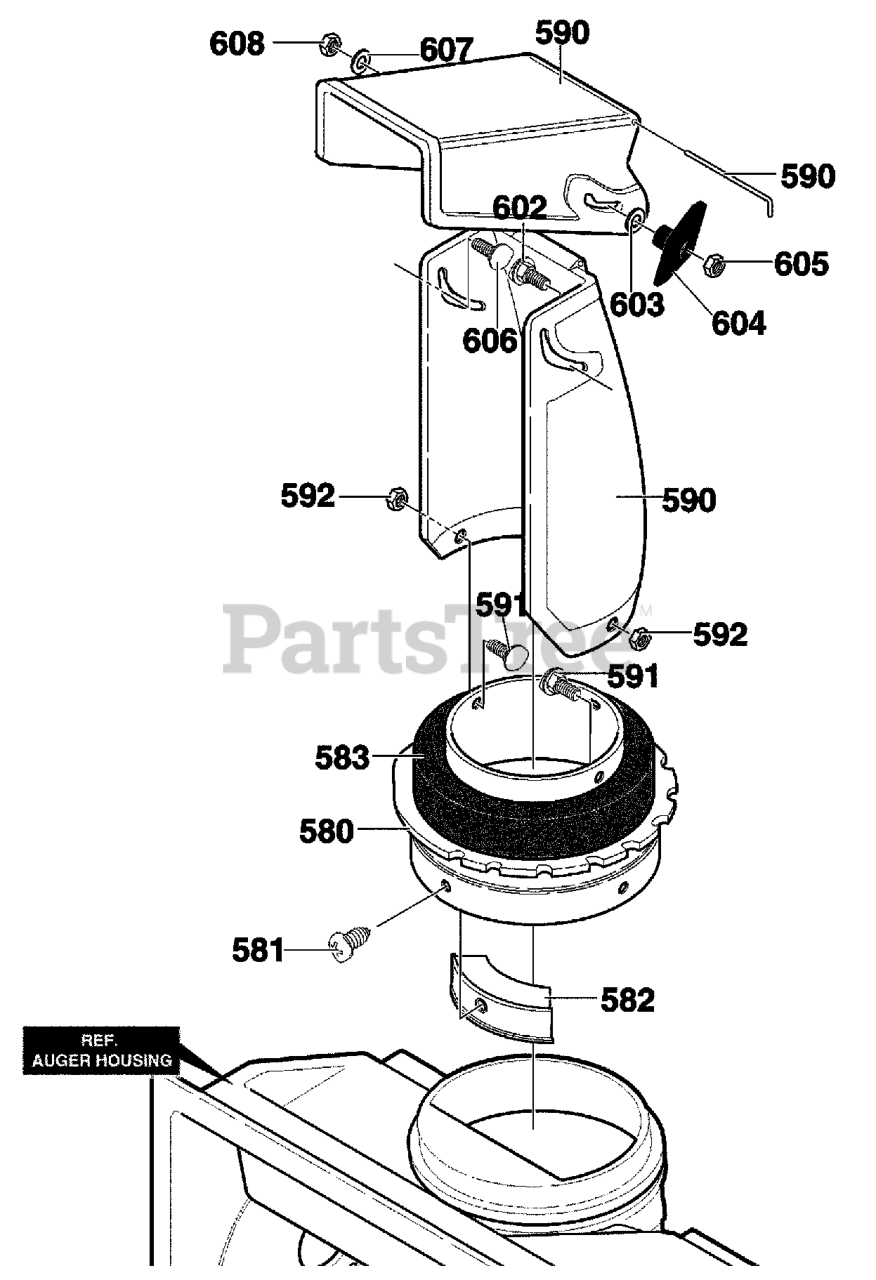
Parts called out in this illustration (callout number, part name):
580	RING, CHUTE
581	SCREW, #10X.50
582	GUIDE, CHUTE
583	DONUT FOAM
590	CHUTE ASSY.
591	SCREW 1/4-20X.50
592	NUT, CNTRLK 1/4-20
602	BOLT, 5/16-18X1.25 CARR.
603	WASHER, FLAT .349X.69X.066
604	KNOB, T
605	NUT, 5/16-18 REGHEX
606	SCREW, 5/16-18 x 0.75
607	WASHER, FLAT .349X.69X.066
608	NUT, 5/16-18 REGHEXCTRLK
